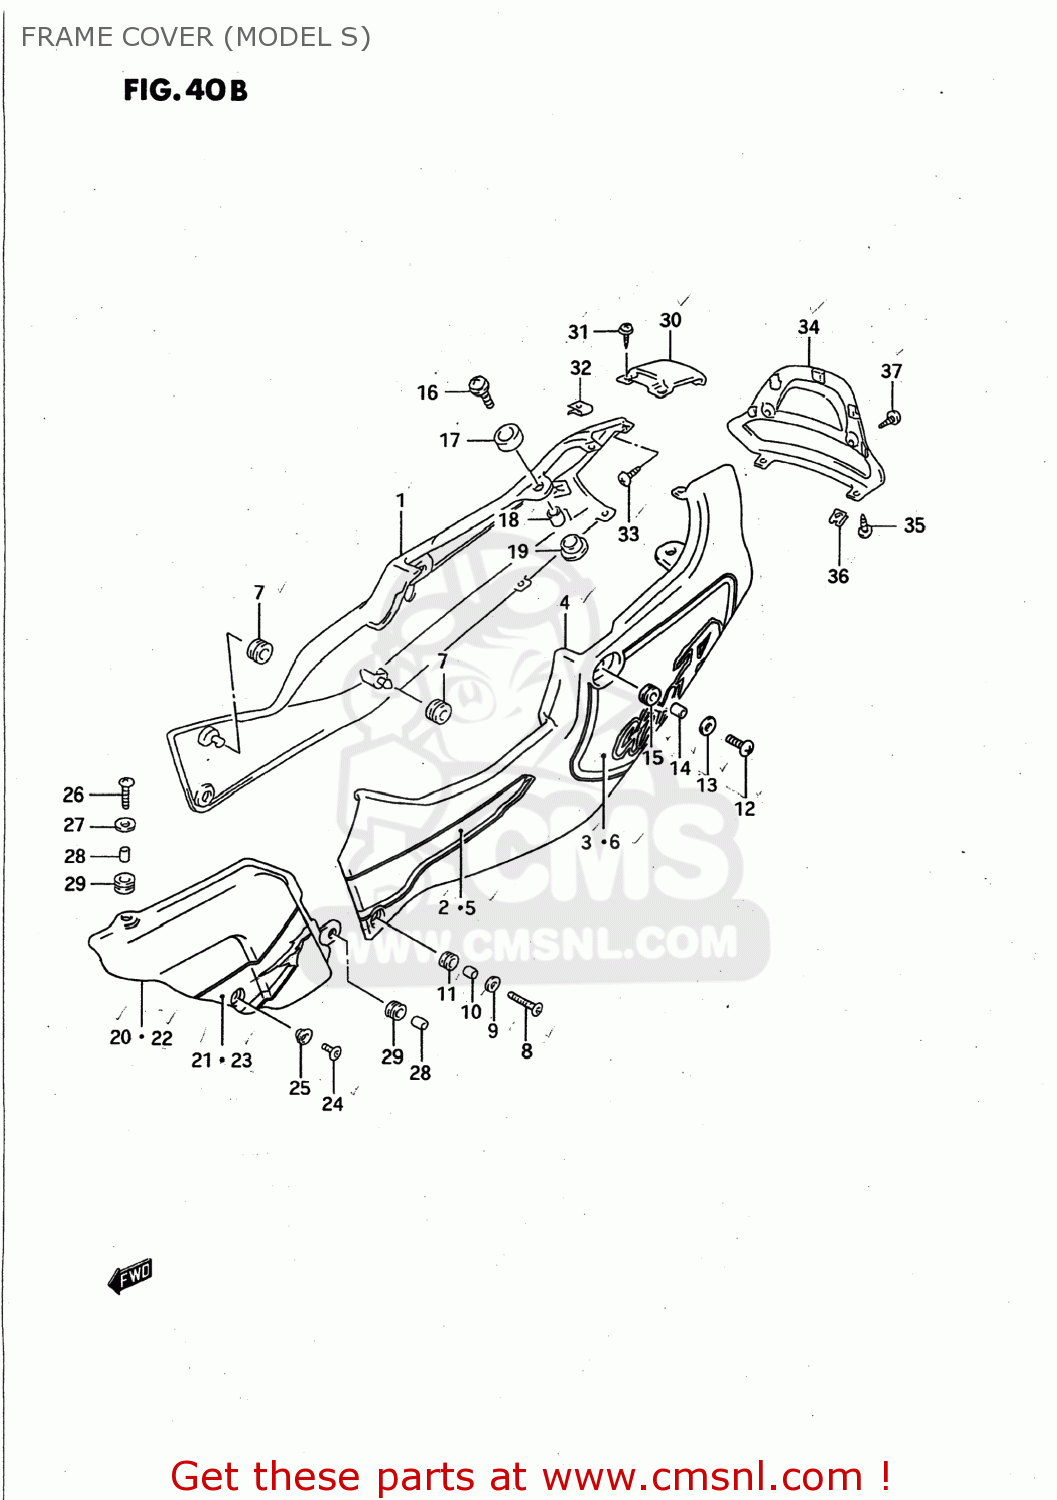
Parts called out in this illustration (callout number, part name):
1	COVER ASSY,FRAME,R(WHITE)
2	TAPE,FRAME COVER,RIGHT
3	TAPE,FRAME COVER ZECKE
4	COVER ASSY,FRAME,L(WHITE)
5	TAPE,FRAME COVER,L
6	TAPE,FRAME COVER STICKER
7	CUSHION
8	SCREW(6X30)
9	WASHER
10	SPACER (6.1X9X9)
11	CUSHION
12	SCREW(6X20)
13	WASHER(6.5X22X1.6)
14	SPACER (6.3X9.1X6.7)
15	CUSHION
16	SCREW(6X30)
17	CUSHION,TAIL COVER UPR
18	SPACER (6,8X10X9.4)
19	CUSHION,FRAME COVER LWR
20	COVER ASSEMBLY,FRAME BODY
21	TAPE,FRAME COVER BODY
22	COVER ASSEMBLY,FRAME BODY
23	TAPE,FRAME COVER BODY
24	SCREW(5X14)
25	WASHER
26	SCREW(6X25)
27	WASHER
28	SPACER (6.1X9X9)
29	CUSHION
30	COVER ASSY,FRAME CTR
31	SCREW
32	NUT
33	SCREW(5X14)
34	COVER,FRAME RR
35	SCREW 5X12
36	NUT
37	SCREW
